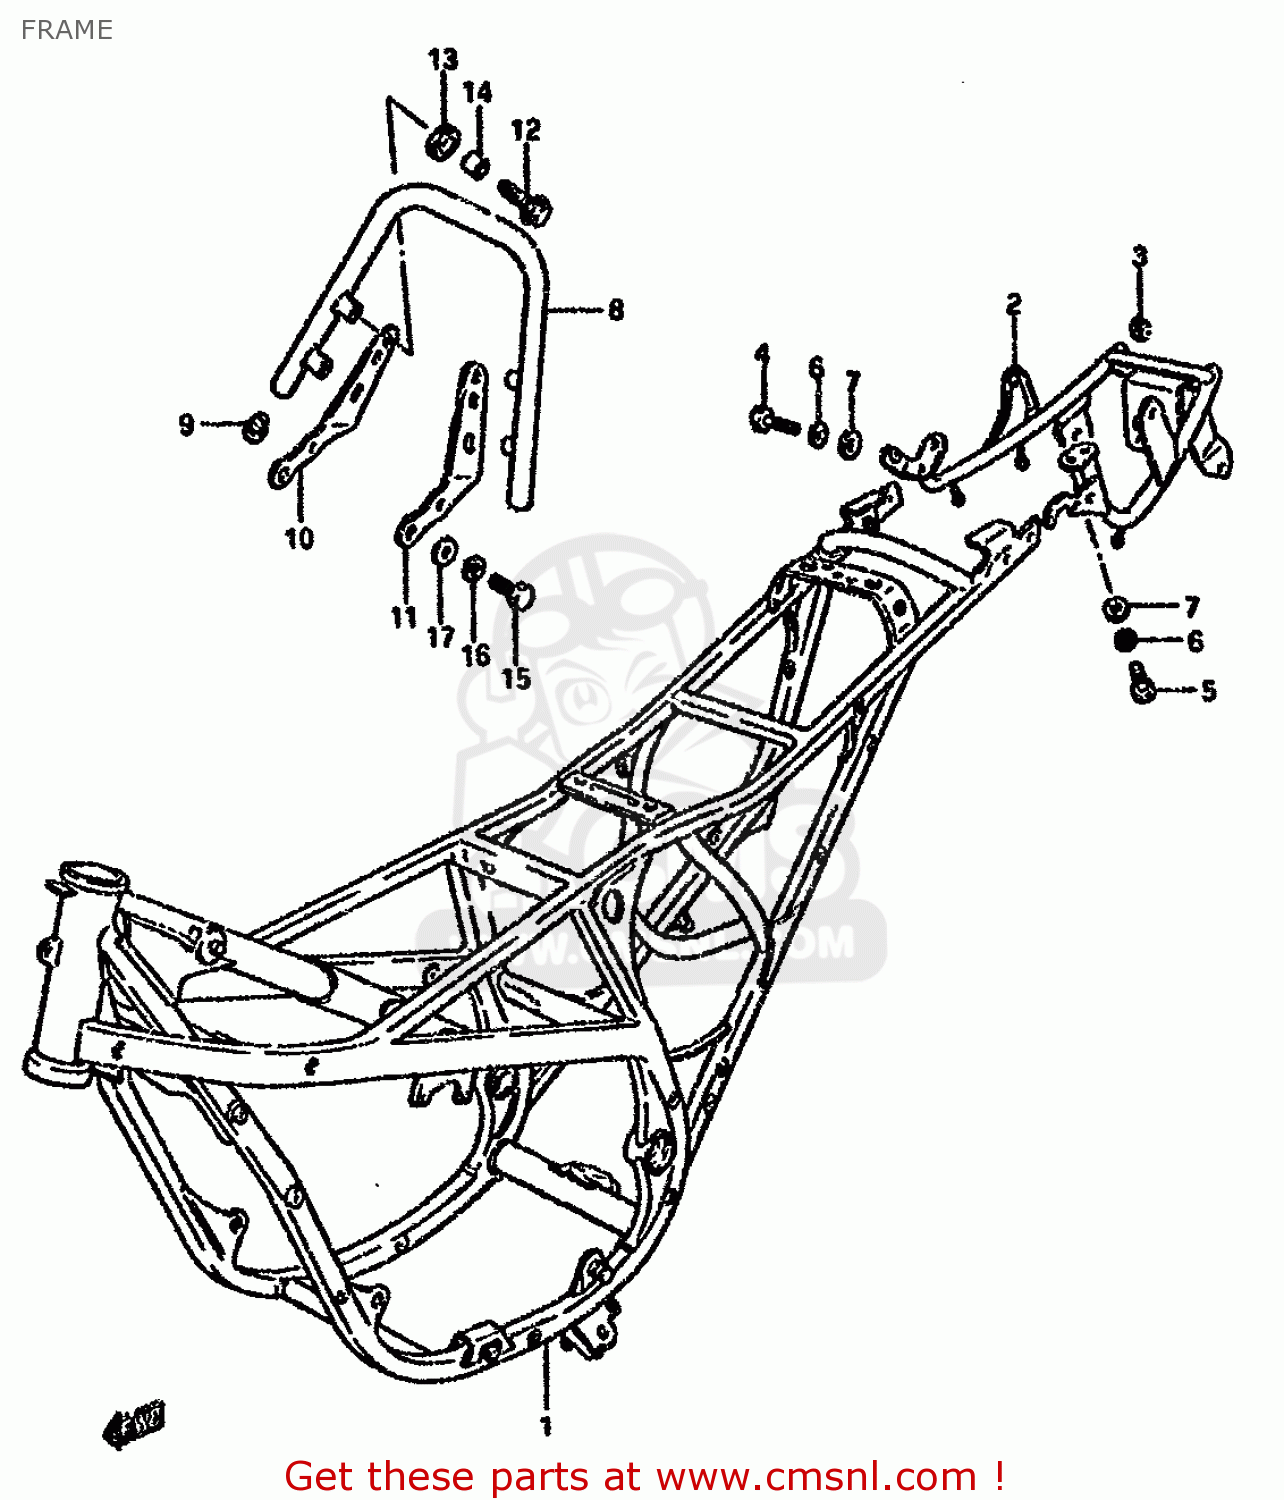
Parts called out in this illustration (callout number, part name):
1	FRAME (SILVER)
2	GRIP, FRAME HANDLE
3	PLUG(OD:17)
4	BOLT
5	BOLT
6	WASHER,LOCK
7	WASHER
8	HANDLE,PILLIO RIDER
9	PLUG(OD:17)
10	PLATE,RH
11	PLTE,LH
12	BOLT
13	CUSHION
14	SPACER
15	BOLT
16	WASHER,LOCK
17	WASHER
